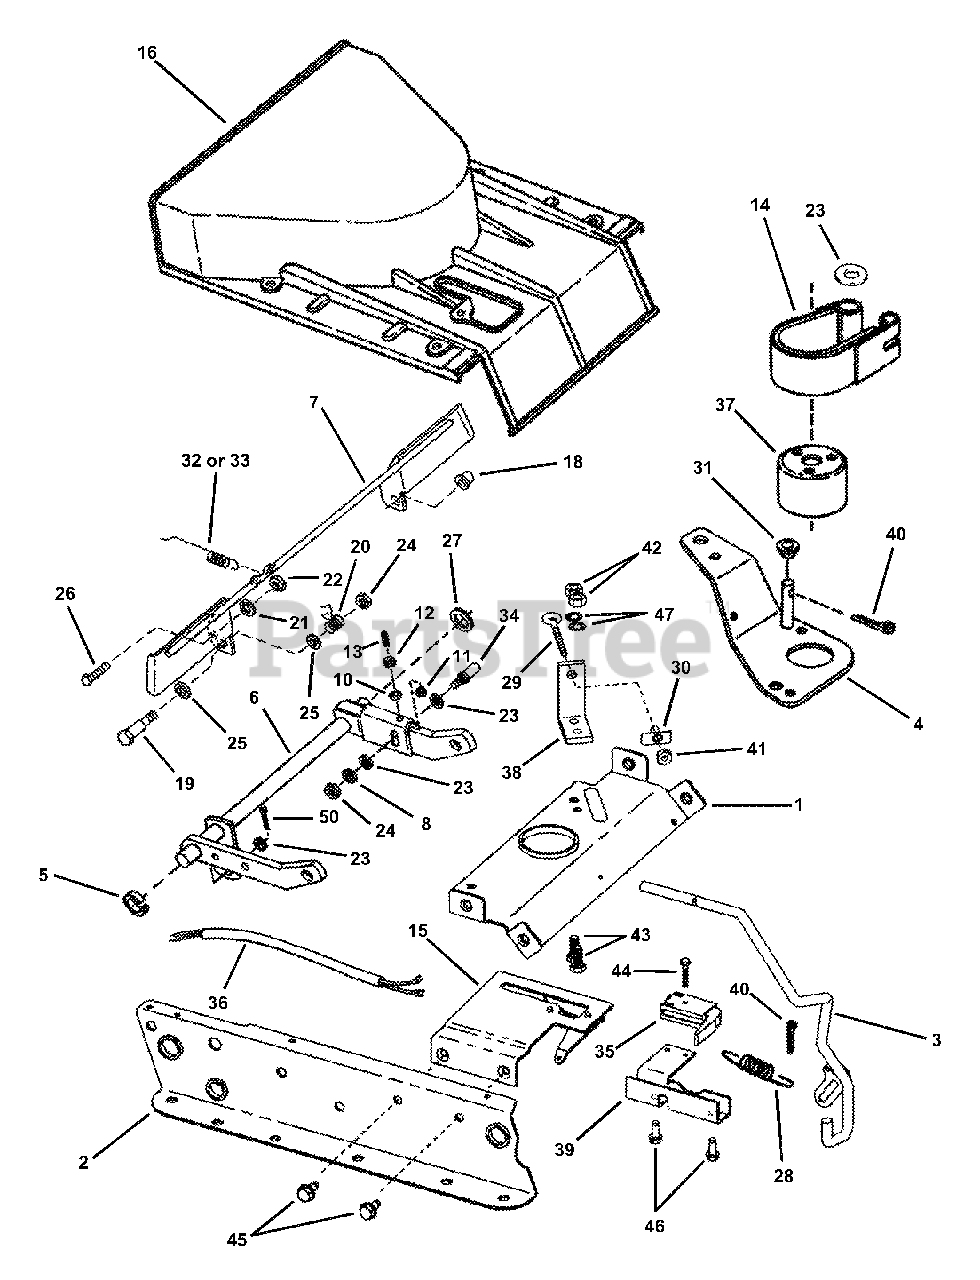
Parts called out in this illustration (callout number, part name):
1	TOP BRACE
2	SIDE RAIL, Right Hand
3	WELDMENT, Blade Engagement Handle
4	WELDMENT, Idler Arm
5	RING, Front Lift Arm- Red
6	WELDMENT, Front Lift Arm
7	WELDMENT, Foot Pedal
8	WASHER, 3/8" Split Lock
9	SCREW, 3/8-24 x 1-1/2" Hex Head Cap
10	WASHER, 5/16" Flat
11	NUT, 5/16-18 Hex
12	NUT, 5/16- Hex Jam
13	SET SCREW, 5/16-18 x 1-1/4" Hex Socket
14	ASSEMBLY, Brake Band
15	ASSEMBLY, Clutch Plate
16	COVER, Spindle
18	PUSH NUT, 1/2"
19	SHOULDER BOLT, 3/8-24 Hex Head
20	SPRING, Pedal
21	WASHER, 1/4" Internal Tooth Lock
22	NUT, 1/4-28 Hex
23	WASHER, 3/8" Flat
24	NUT, 3/8-24 Hex
25	WASHER, 1/2" Flat
26	SCREW, 1/4-28 x 1" Hex Head Cap, Grade 5
27	WASHER, .77 I.D. x 1.13 O.D. x .06 Thick
28	SPRING, Blade Handle
29	EYE BOLT, 1/4-20 Thread
30	T-NUT, 1/4-20
31	SPACER, Nylon
32	LATCH SPRING
33	LATCH SPRING
34	BOLT, 3/8-24 Hex Head Shoulder
35	SWITCH
36	DECK WIRE
37	DRUM, Brake
38	ANCHOR
39	MOUNT, Switch
40	PIN, 3/32 x 3/4" Cotter
41	NUT, 1/4-20 Hex, Grade 5 or B
42	NUT, 5/16-24 Hex, Gr. 5 or B
43	SCREW, 5/16-24 x 3/4" Hex Head Cap
44	SCREW, #10-32 x 1" Hex Washer Self-Tap
45	SCREW, 5/16-18 x 5/8" Hex Washer Self-Tap
46	SCREW, 1/4-20 x 5/8" Hex Washer Self-Tap
47	WASHER, 5/1g" Internal Tooth Lock
48	PIN, 1/4 x 1-5/8" Clevis
49	WASHER, 1/4" Flat
50	PIN, 1/8 x 3/4" Cotter
